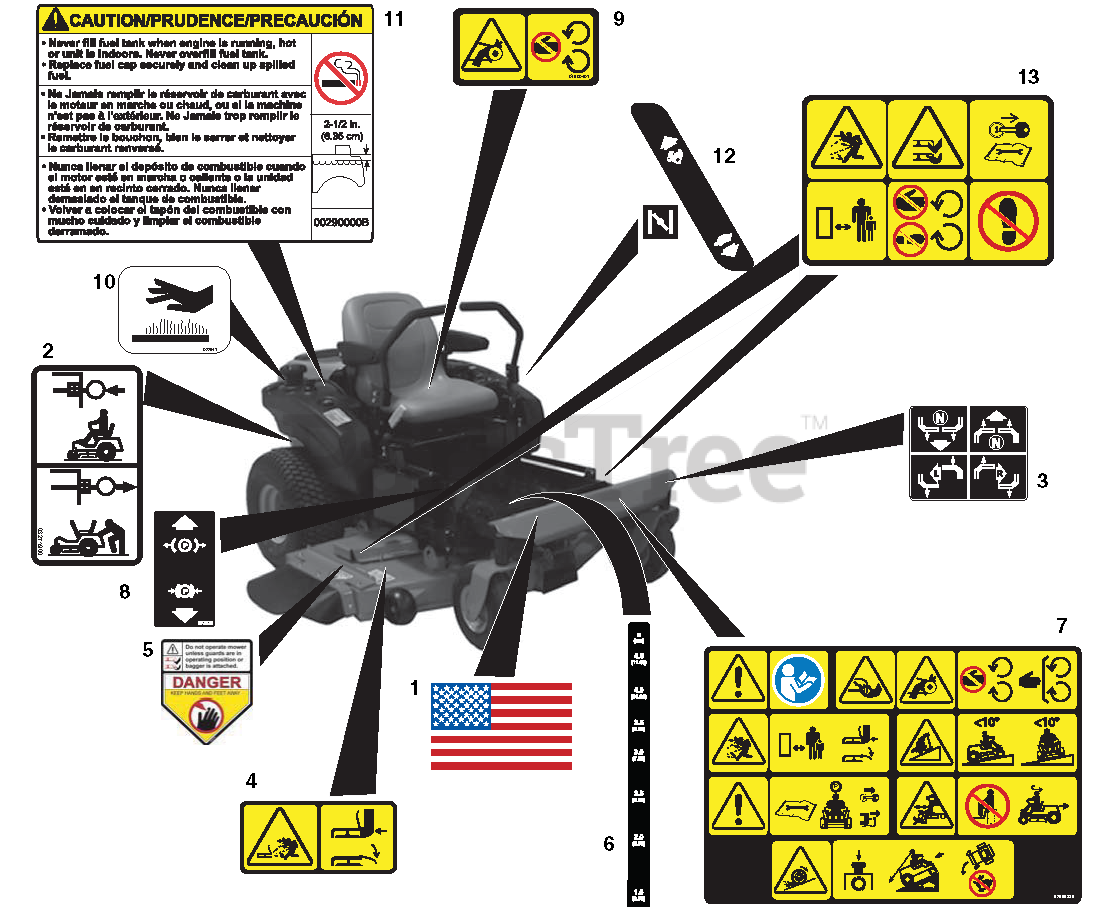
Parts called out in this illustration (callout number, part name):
1	DECAL, AMERICAN FLAG
2	DECAL, TRANSMISSION DISCONNECT
3	DECAL, INSTRUCTIONAL-STEERING
4	DECAL, SAFETY - DECK GUARDING
5	DECAL, DANGER
6	DECAL, CUT HEIGHT XL
7	DECAL, SAFETY - MAIN
8	DECAL, PARKING BRAKE LEVER
9	DECAL, SAFETY - GUARDING
10	DECAL, HOT SURFACE
11	DECAL,FUEL WARNING
12	DECAL, SPEED CONTROL
13	DECAL, SAFETY - MOWER DECK
